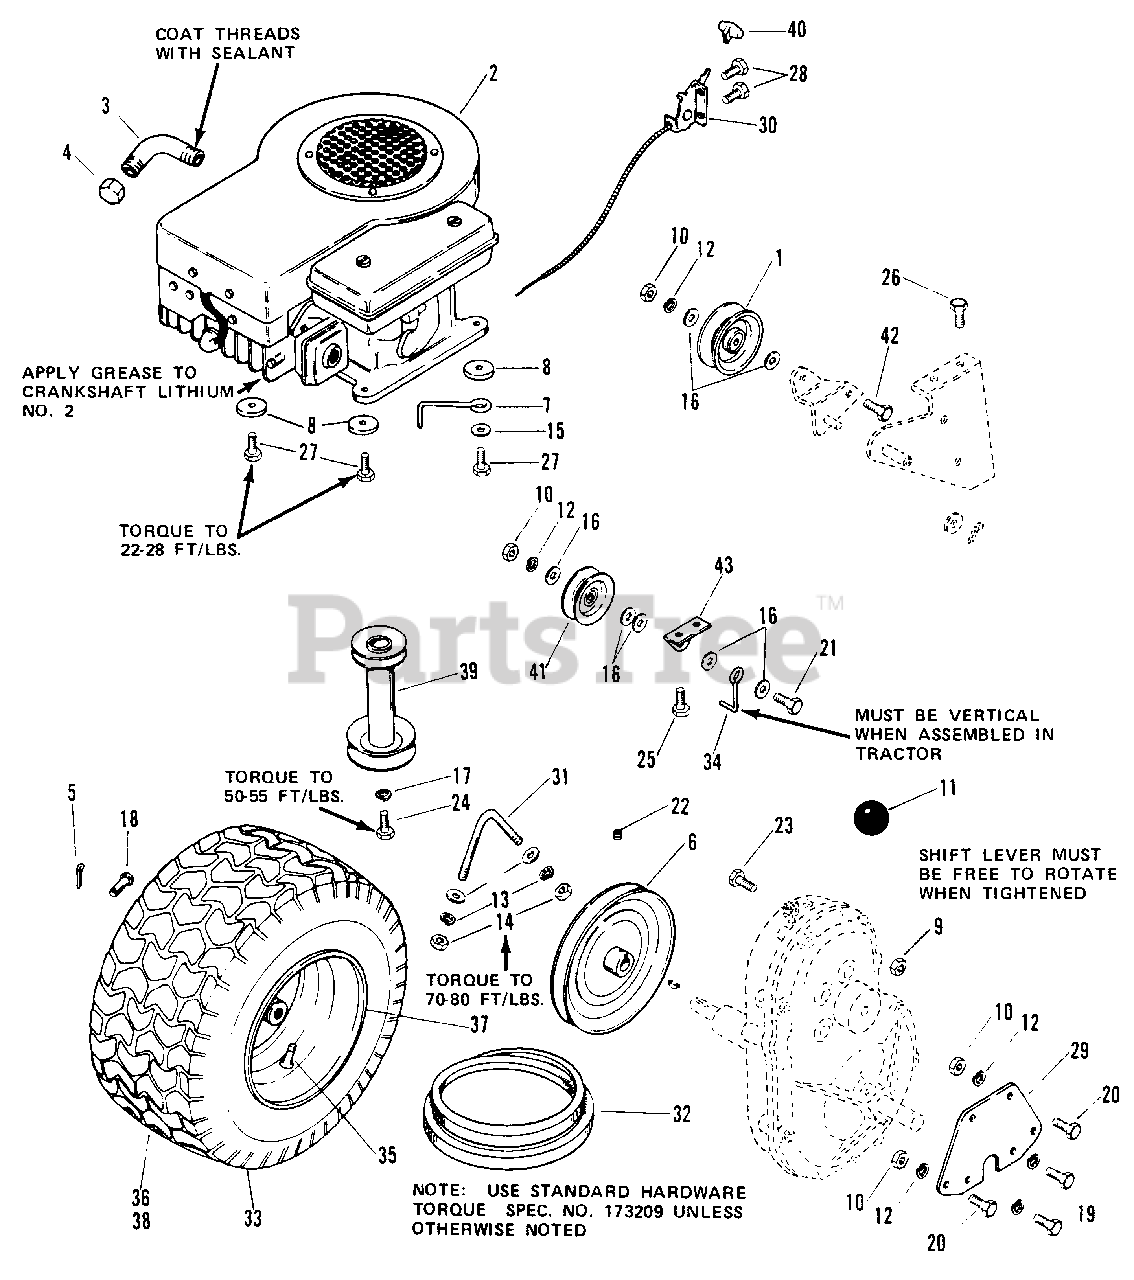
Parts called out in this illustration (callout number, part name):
1	PULLEY, Idler
2	ENGINE, 8 HP, Briggs & Stratton, Model 191707, Type 5148-01, Synchro-Balanced
3	PIPE, Oil Drain
4	CAP, Pipe, 3/8
5	PlN
6	PULLEY, Transmission
9	LOCKNUT, Center, 1/4
10	NUT, Hex, Full, 3/8-16
12	LOCKWASHER, 3/8
13	LOCKWASHER, 5/16
14	NUT, Hex, Full, 5/16-18
15	WASHER, Plain, 3/8
16	WASHER, Plain, 5/16
17	LOCKWASHER, 7/16
18	PIN, Cotter, 1/8 x 3/4
19	CAPSCREW, Hex, 3/8-16 x 1
20	CAPSCREW, Hex, 3/8-16 x 3/4
21	CAPSCREW. Hex, 3/8-16 x 1-1/2
22	SCREW, Sq. Hd., Set. 3/8-24 x 3/8
23	CAPSCREW, Hex Hd. 1/4-20 x 1
24	CAPSCREW, Hex, Hd., 7/16-20 x 1-1/4
25	SCREW, Taptite, Washer Hd., 1/4-20 x 3/8
26	SCREW, Taptite, Hex Washer, 5/16-18 x 5/8
27	SCREW, Hex Taptite, Washer Hd., 3/8-16 x 1-3/4
28	SCREW, Taptite, 1/4-20 x 3/4
29	BRACKET, Support
30	THROTTLE, Control
31	BOLT, Axle
33	WHEEL & TIRE, 18 x 8.50-8
35	VALVE STEM & CAP
36	TlRE, 18 x 8.50-8 (Goodyear)
37	WHEEL ASSEMBLY
38	TIRE, 18 x 8.50-8 (Carlisle)
39	PULLEY, Engine
40	KNOB, Throttle
41	PULLEY, Idler
42	CAPSCREW, Hex, 3/8-16 x 1-1/4
43	BRACKET, Idler
